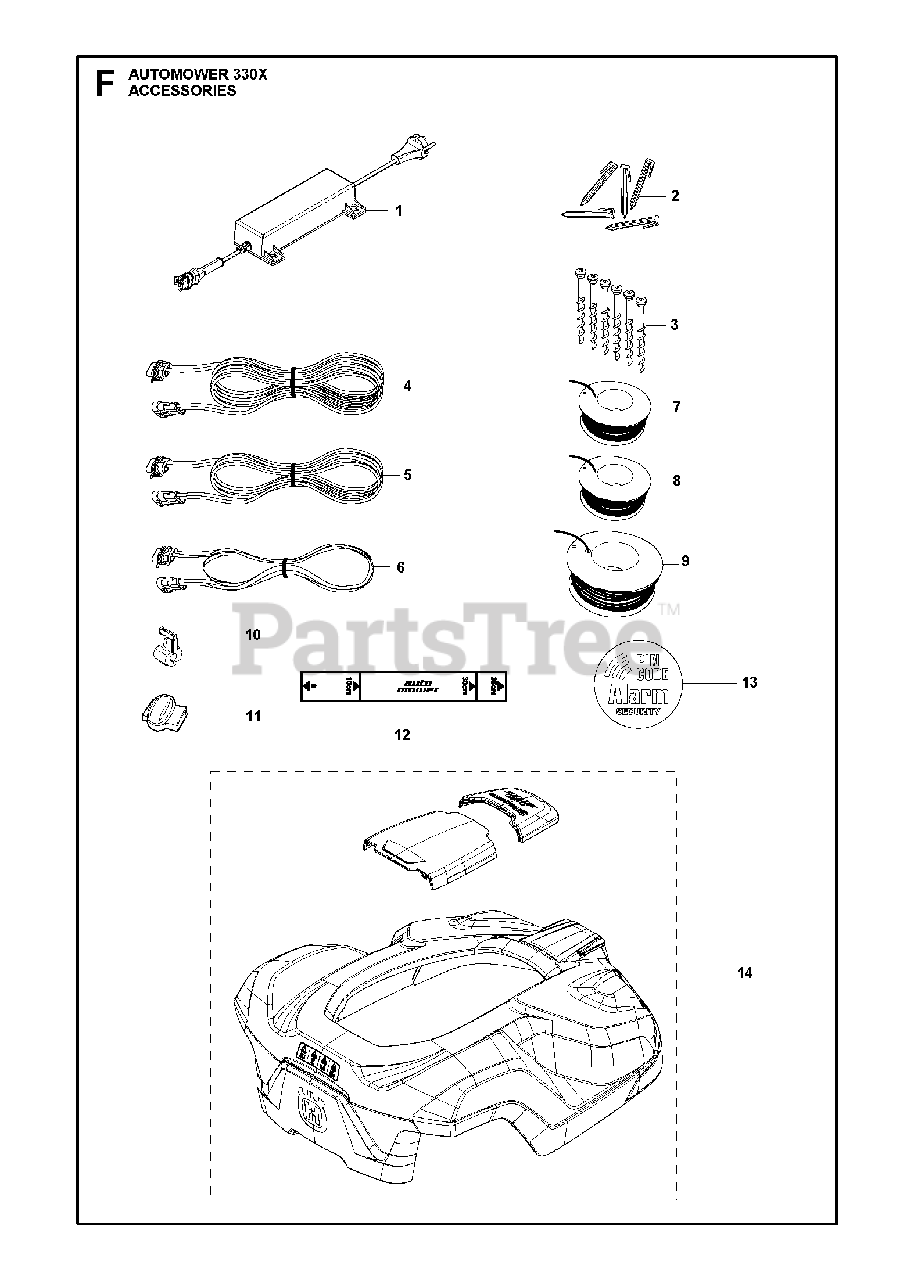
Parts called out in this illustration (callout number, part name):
2	STAPLES (100 CT BAG)
2	STAPLE 100 PCS BLISTE
3	SCREW KIT CS
3	SCREW 3 PCS, BLISTER PACK
4	LOOM LOW VOLTAGE CABLE 20 METE
5	LOOM LOW VOLTAGE CABLE 10 METE
6	LOOM LOW VOLTAGE CABLE 3 METER
7	LOOP WIRE 150M
7	WIRE 150M BLISTER
8	LOOP WIRE 250M
9	Wire, 500M
10	BRAKER
10	Connector, 5 Pcs Blist
11	SPLICE KIT
11	Splicer Coupler, 5 Pcs
11	SPLICE CONNECTOR 50 PCS/PK
12	RULER / CENTIMETERS
13	LABEL SECURITY
